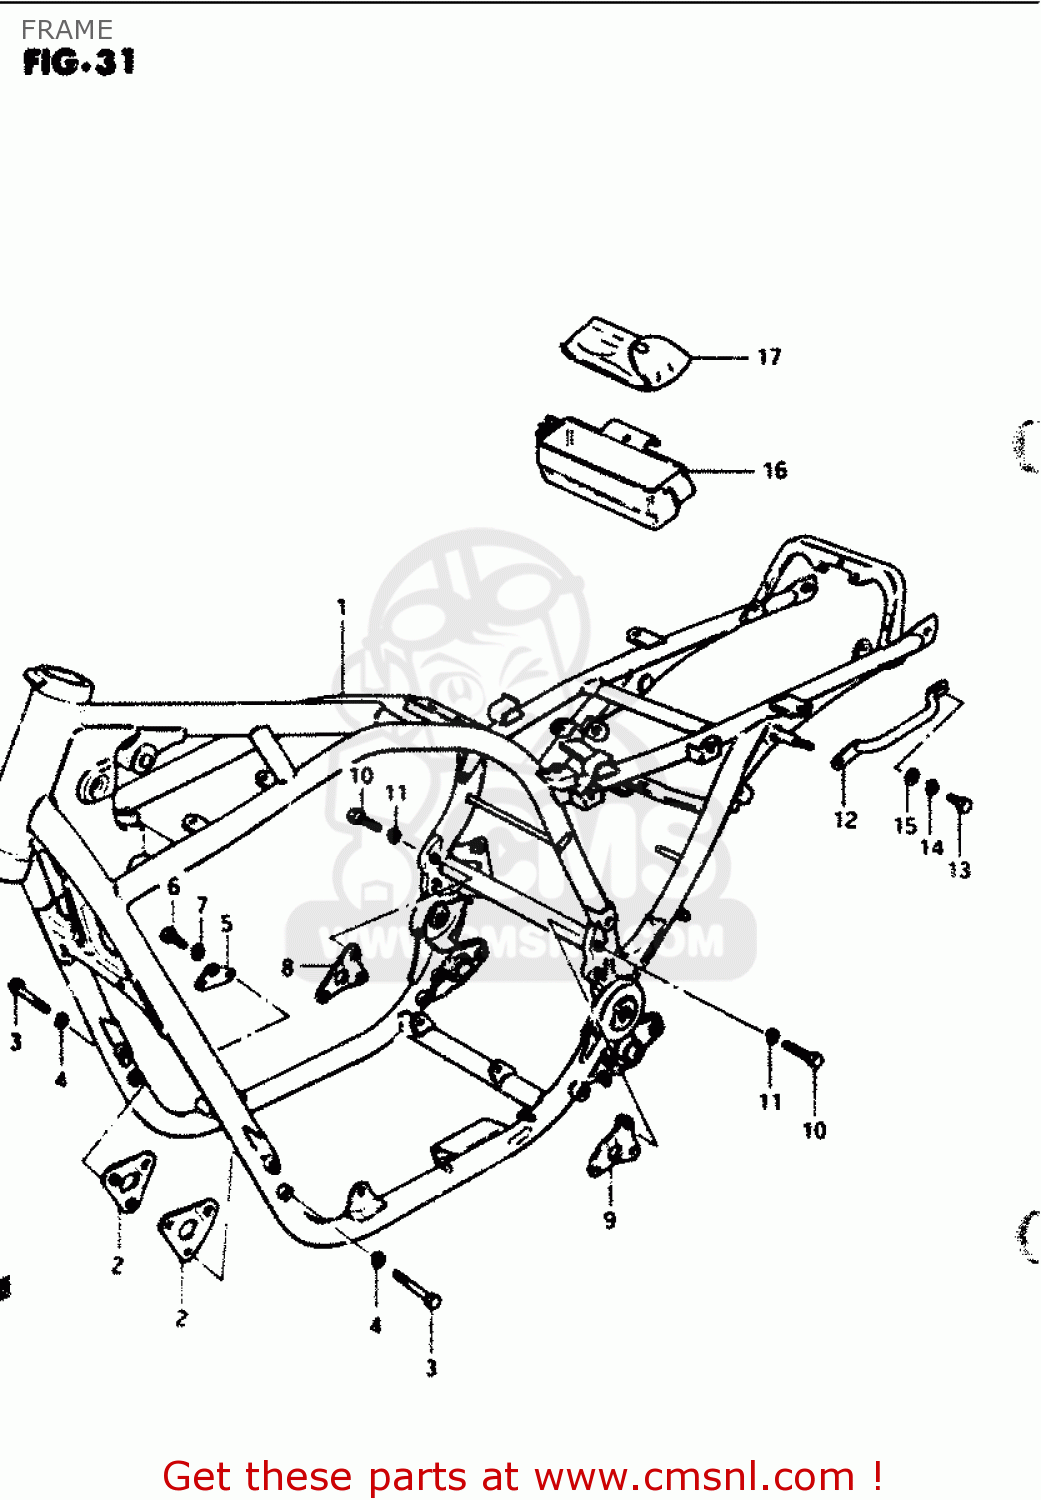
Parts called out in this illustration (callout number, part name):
1	FRAME (BLACK)
2	PLATE,ENGINE MOUNTING
3	BOLT
4	WASHER,LOCK,8.
5	PLATE,ENGINE MOUNTING
6	BOLT
7	WASHER,LOCK,8.
8	PLATE,ENGINE MOUNTING
9	PLATE,ENGINE MOUNTING
10	BOLT 8X40
11	WASHER,LOCK,8.
12	GRIP,FRAME HANDLE
13	BOLT,8X16
14	LOCK WASHER
15	WASHER
16	HOLDER,TOOL
17	TOOL SET
